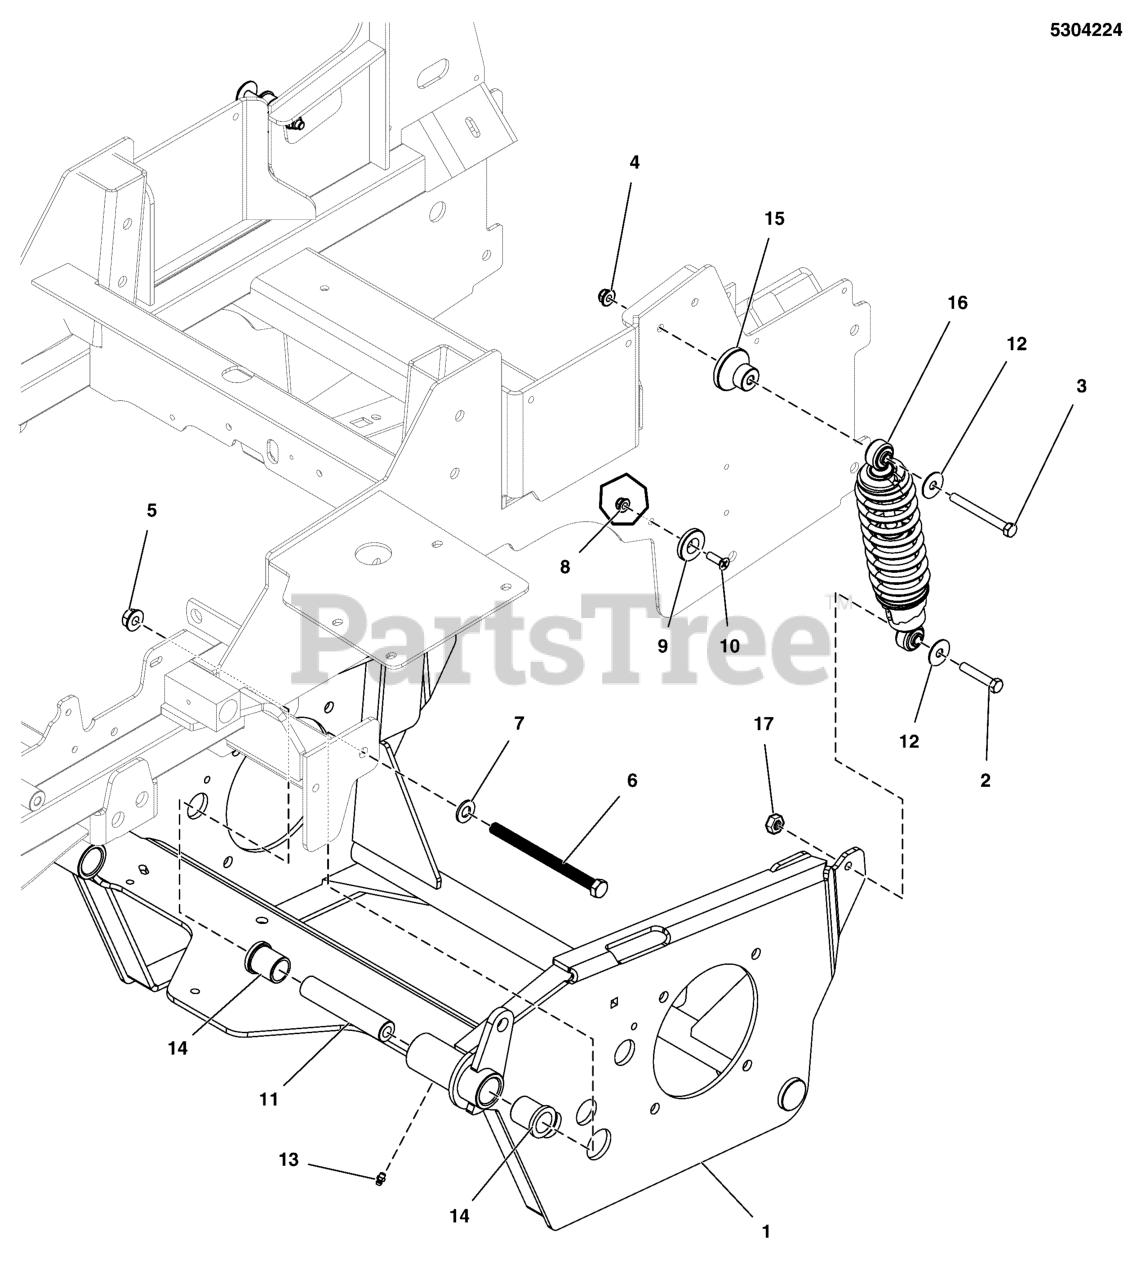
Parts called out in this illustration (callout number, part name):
1	CRADLE, Suspension
2	BOLT, 3/8-16 X 2, GD5, CZ
3	BOLT, 3/8-16 X 3-1/2" GD5 CZ
4	NUT, 3/8-16 HEX NYLOCK FLANGE
5	NUT, Hex Flange, Nylock, 1/2-13
6	BOLT, 1/2-13 X 6-1/2 GD8, CZ
7	WASHER, 1/2 SAE
8	NUT, 5/16-18 HEX NYLOCK FLANGE
9	SPACER, .34 X 1.54 X .25, PL
10	SCREW, 5/16-18X1, PHILLIPS HD. BZ
11	SPACER, .52 X 1.00 X 5.00
12	WASHER-3/8 FENDER
13	GREASE FITTING, 1/4-28 STRAIGHT
14	BUSHING, FLANGE
15	SPACER, .39 X 2.00 X 1.35, PM
16	SHOCK / SPRING ASSEMBLY, OE22376
17	NUT, 3/8-16 HEX SIDE LOCK
